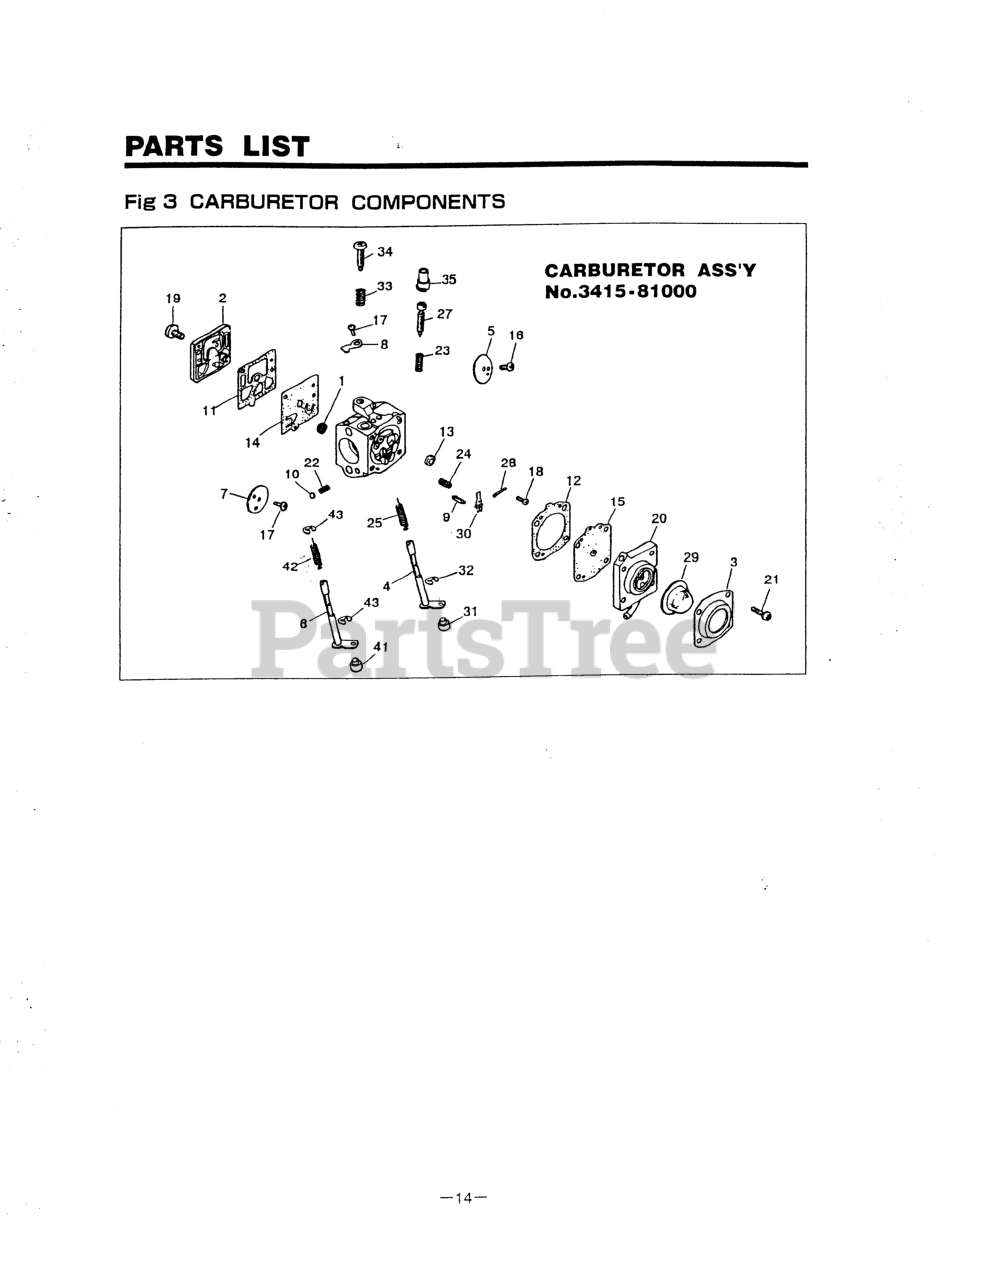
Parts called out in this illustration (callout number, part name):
2	COVER, PUMP
3	COVER, PUMP
4	SHAFT ASSEMBLY
6	SHAFT, CHOKE
7	VALVE, CHOKE
8	THROTTLE STOP
9	VALVE, INLET
10	BALL, FRICTION
11	KIT ONLY
12	KIT ONLY
13	PLUG, WELSH
14	KIT ONLY
20	BODY ASSY (RPLS 1491-81490)
21	SCREW (REPLACES 1491-81350)
22	SPRING
24	KIT ONLY
25	SPRING
27	NEEDLE (NLA)
28	PIN, METERING LEVER
29	PUMP, PRIMER
30	KIT ONLY
31	SWIVEL (USE -06040)
33	SPRING, IDLE
